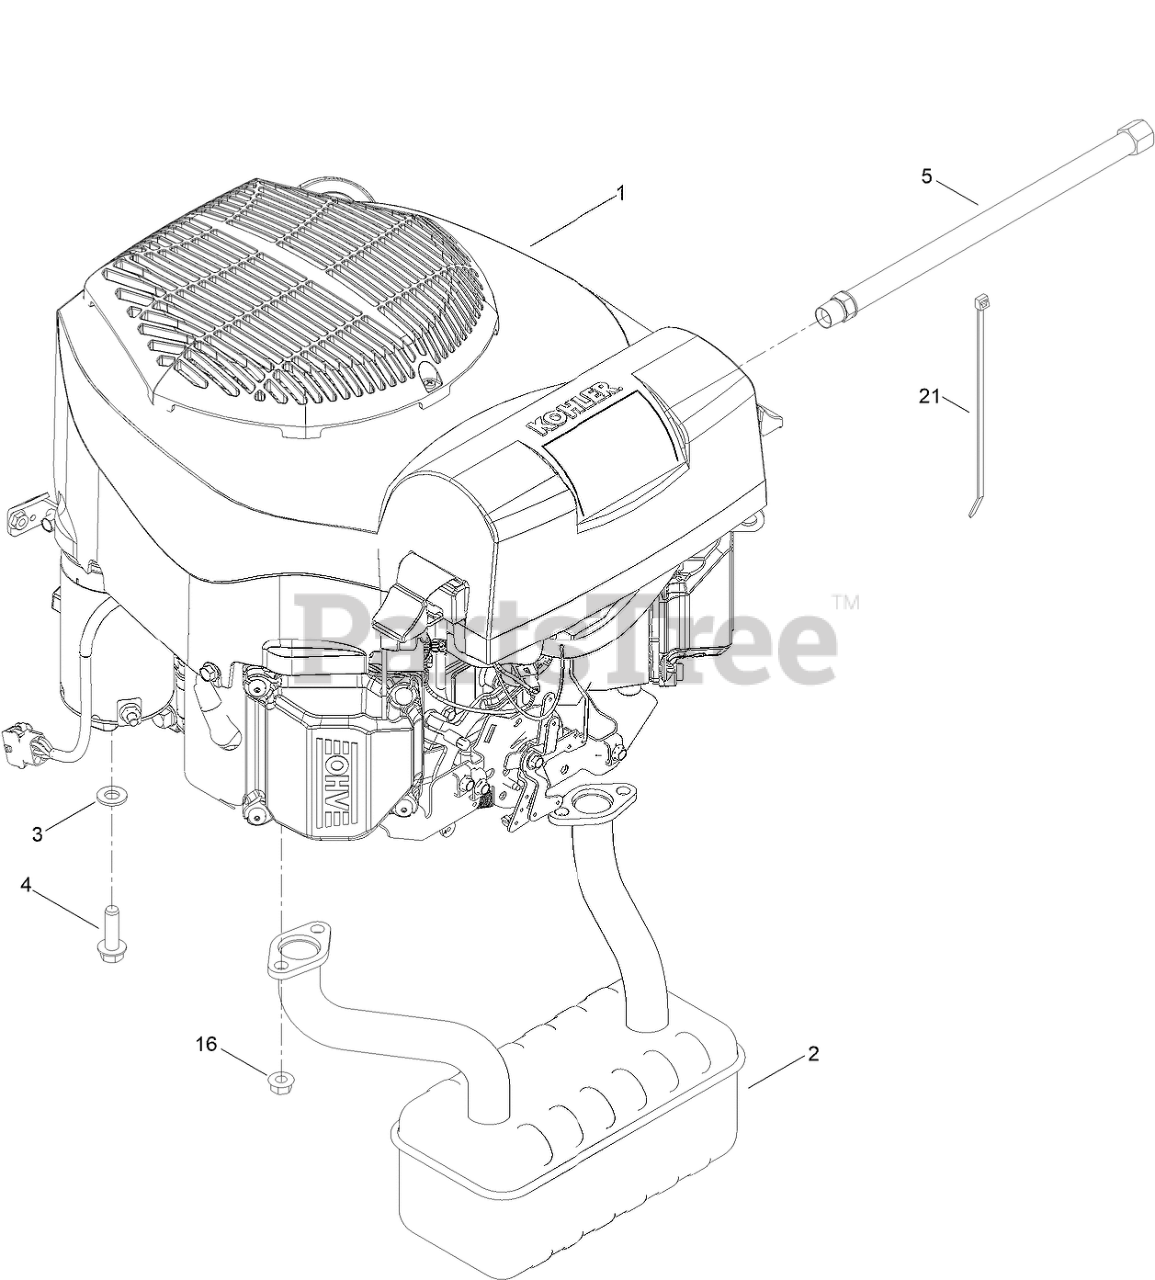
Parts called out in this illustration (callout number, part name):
2	MUFFLER
3	WASHER-FLAT
4	SCREW-THD
5	HOSE-DRAIN, OIL
16	NUT-HF
21	TIE-CABLE
